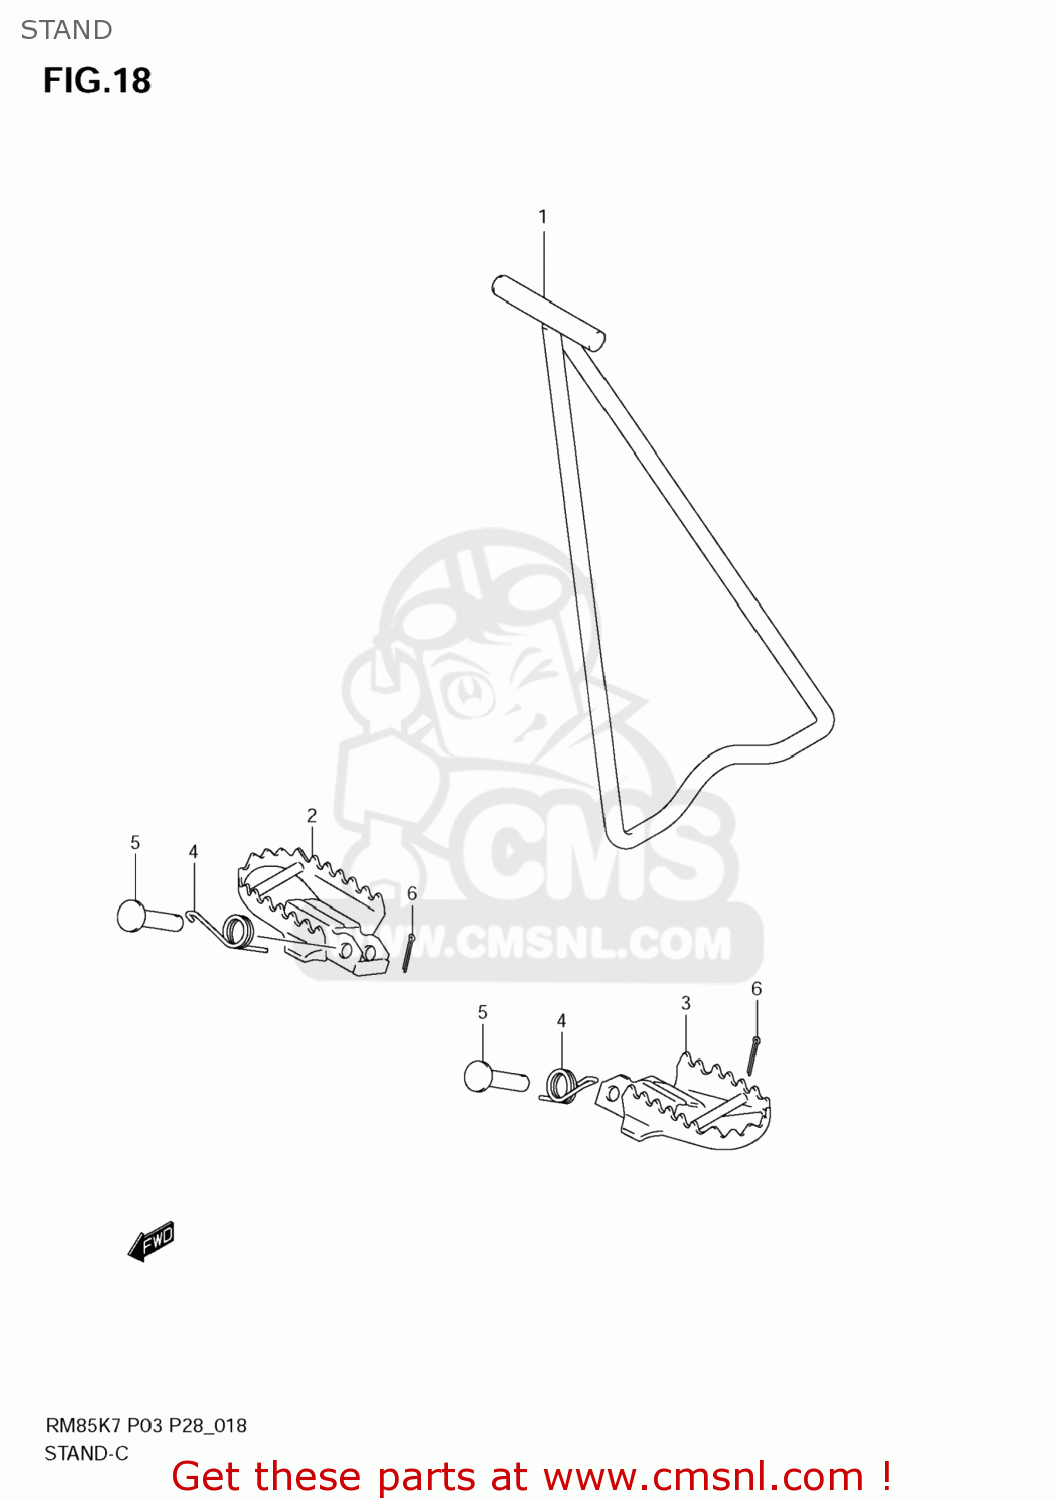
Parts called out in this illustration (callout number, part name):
1	STAND
2	FOOTREST,R
3	FOOTREST,L
4	SPRING
5	PIN
6	PIN
